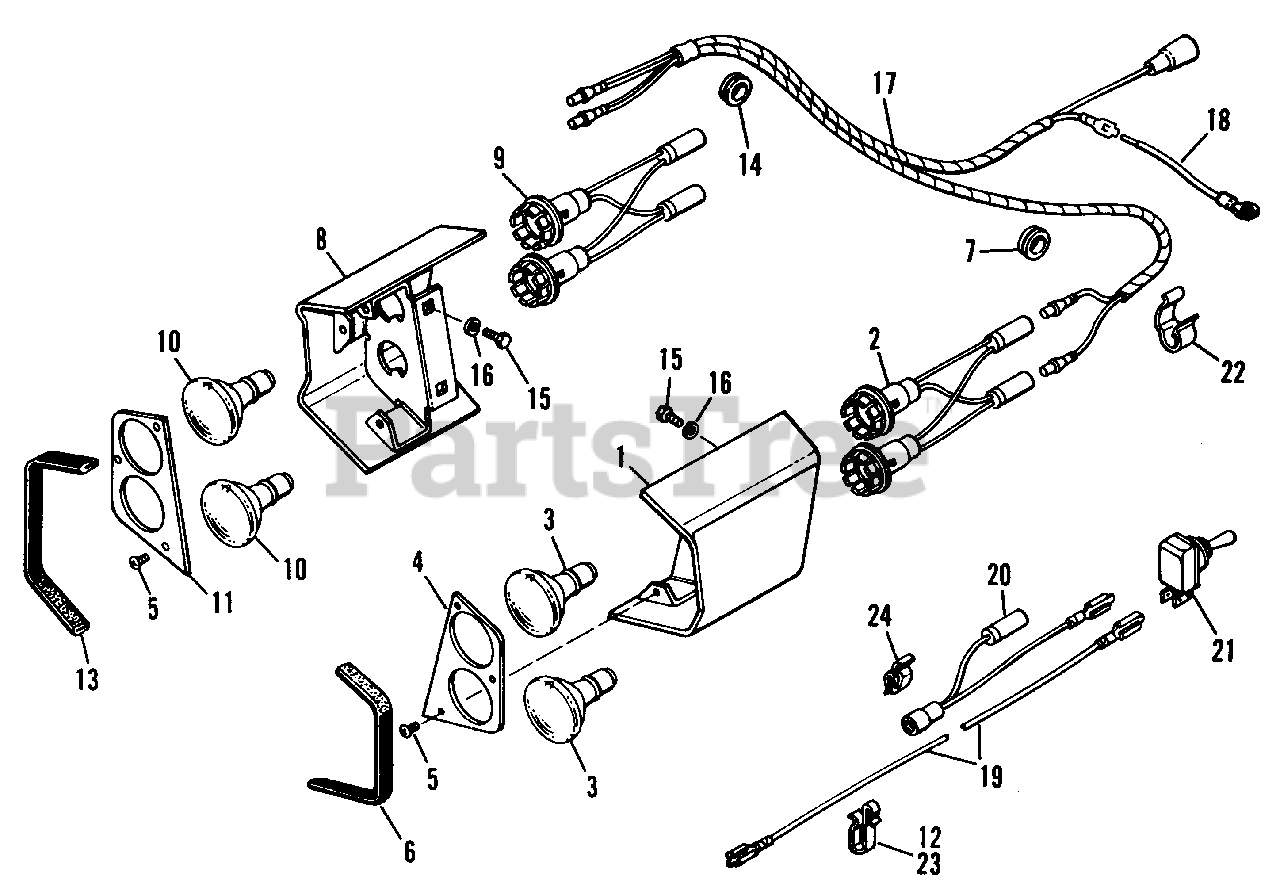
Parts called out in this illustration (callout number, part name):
1	Shroud & Plate Assy., L.H.
2	Lamp Socket & Wire Assembly
3	Headlight
4	Plate, Front
5	Screw, Round Head Phillips Swageform No. 12-24 x 1/2"
8	Shroud & Plate Assy., R.H.
9	Lamp Socket & Wire Assy.
10	Headlight
11	Plate, Front
12	Cable Clip Tinnerman
15	Hex Capscrew, 1/4"-20 x 3/4"
16	Lockwasher, 1/4" Std.
17	Harness Assembly
18	Wire Assy., Ground
19	Wire Assy., Light Switch
20	Wire Assy., Indicator Lamp
21	Switch, Toggle
22	Cable Clip Tinnerman, Front Frame
23	Cable Clip Tinnerman, Rear Frame
24	Cable Clip Tinnerman, Top of Grille
